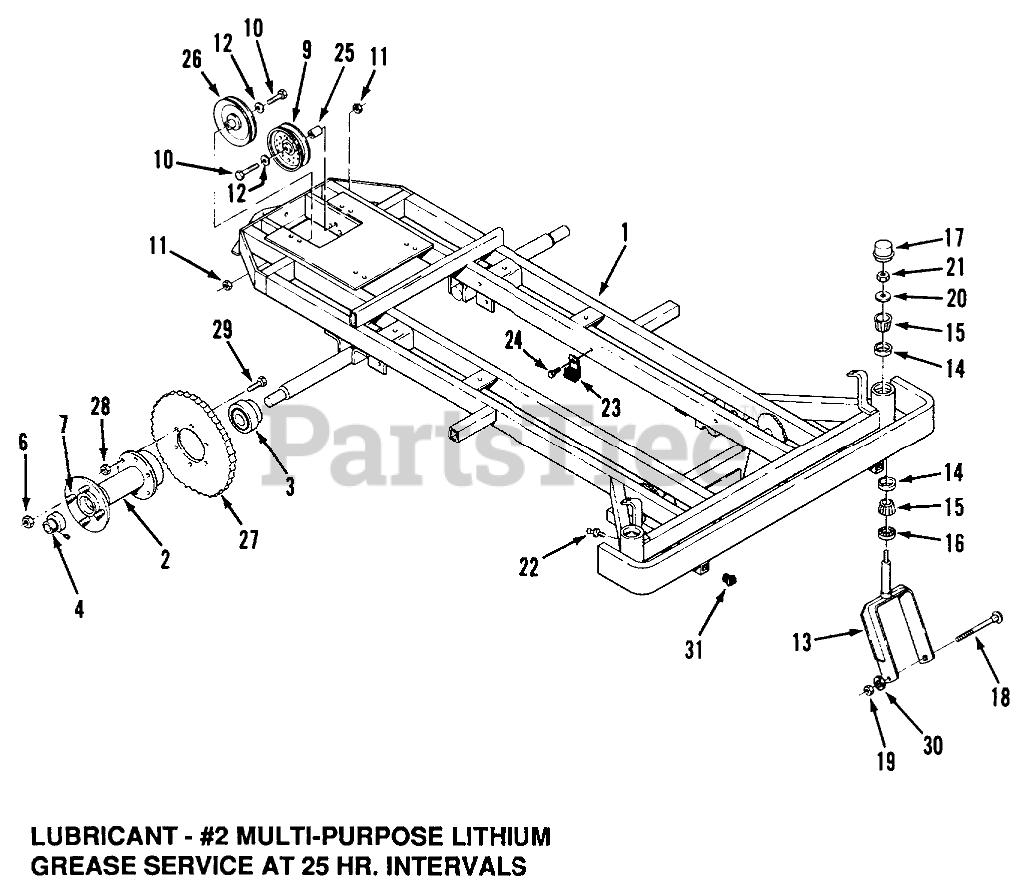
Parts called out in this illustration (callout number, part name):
1	ASS'Y-FRAME B
2	Hub-Rear Wheel
3	BEARING-REAR AXLE
4	BEARING-REAR AXLE
6	Nut-Lug 1/2-20
7	Wheel Stud 1/2-20 x 1-1/4
9	PULLEY FLAT B
10	Bolt
11	NUT
12	Washer
13	Front Wheel Fork
14	Cup
15	Bearing
16	SEAL-FRONT WHEEL
17	DUST CAP
18	Bolt 5/8 11 x 7
19	Nut 5/8-11
20	Washer
21	Nut
22	Fitting-Grease
23	CLIP
24	Bolt
25	BUSHING
26	PULLEY-IDLER V
27	SPROCKET-REAR HUB B
28	NUT
29	Bolt
30	Lockwasher
31	PLUG-SQUARE PLASTIC
